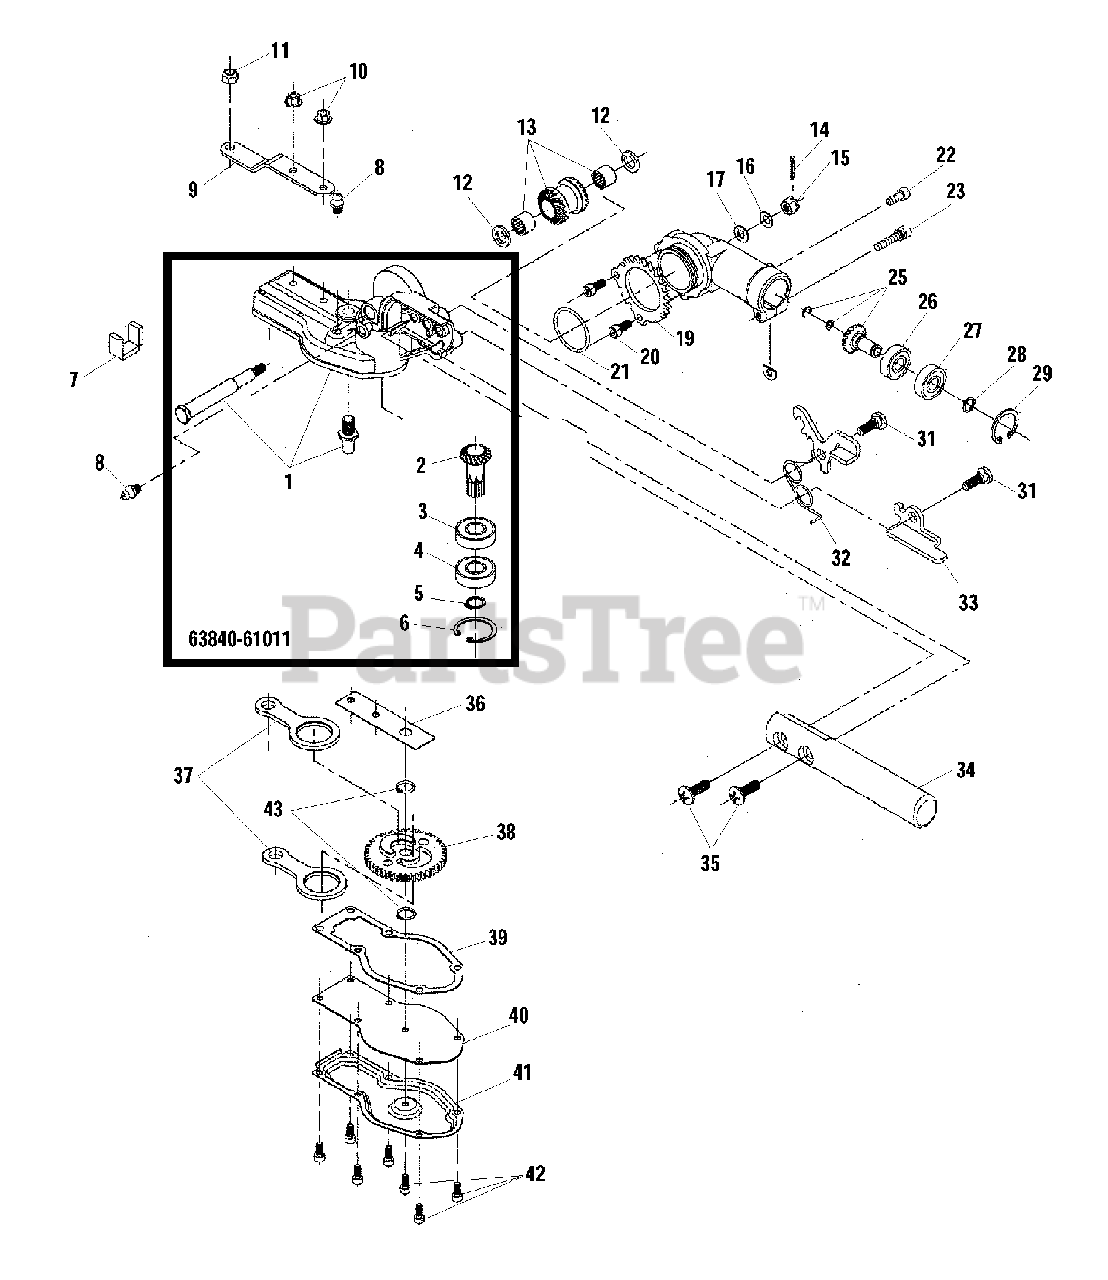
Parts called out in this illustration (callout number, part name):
1	CASE, GEAR - LOWER
2	GEAR - SHAFT
3	BEARING, BALL - 6001
4	BEARING, BALL - 6001ZZ
5	RING, RETAINING - 12
6	RING, RETAINING - 28
7	SEAL, FELT
8	FITTING, GREASE
9	BRACKET, CUTTER
10	NUT - 5 -- FLANGE
11	LOCKNUT - 6
12	COLLAR
13	GEAR SET - BEVEL
14	PIN, SPLIT
15	NUT - CASTLE
16	WASHER - CONICAL
17	WASHER - 6
18	CASE, GEAR - UPPER
19	PLATE, ADJUST
20	SCREW - 5X12
21	O-RING
22	SCREW - 5X12
23	SCREW - 5X25
24	SHIM
25	GEAR - BEVEL
26	BEARING, BALL - 609
27	BEARING, BALL - 609ZZ
28	RING, RETAINING
29	RING, RETAINING - 24
30	LEVER, LOCK
31	SCREW
32	SPRING
33	LEVER, LOCK
34	HANDLE
35	SCREW - 6X20
36	PLATE, GUIDE
37	ROD, CONNECTING
38	CAM GEAR
39	GASKET
40	PLATE, GEAR CASE
41	CASE, GEAR - LOWER
42	SCREW - 4X10
43	SPACER
63840-61011	GEAR CASE ASSY
